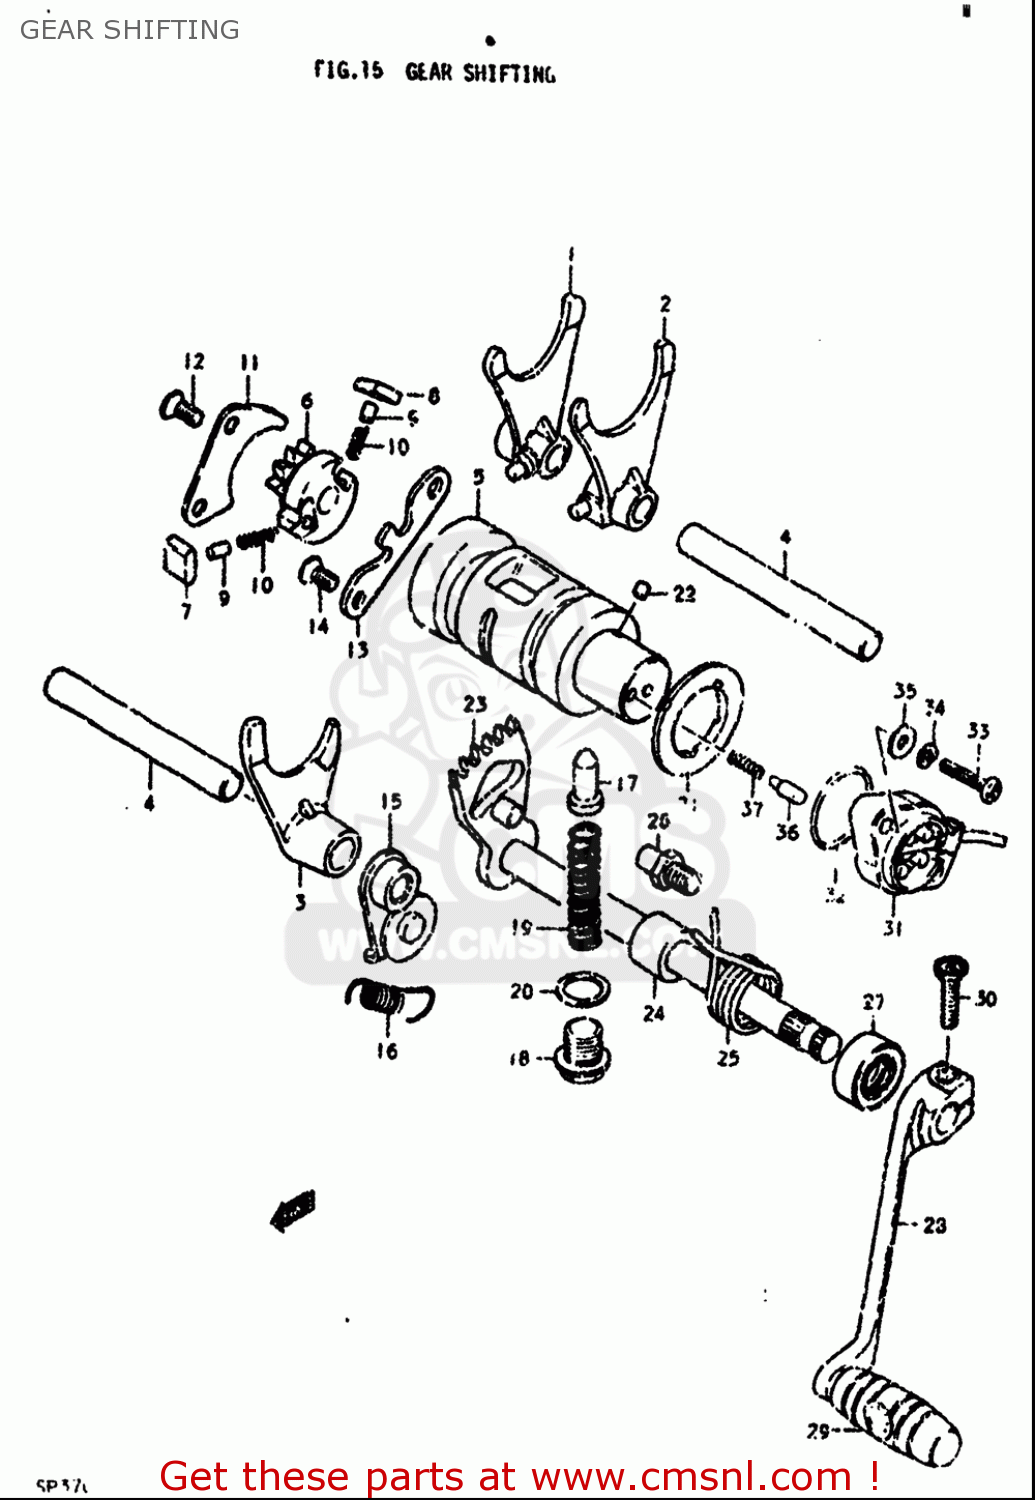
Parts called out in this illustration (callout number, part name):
1	FORK,GEAR SHIFT NO.1
2	FORK,GEAR SHIFT NO.2
3	FORK,GEAR SHIFT NO.3
4	SHAFT,GEAR SHIFT FORK
6	GEAR,GEAR SHIFT CAM DRIVEN
7	PAWL,GEAR SHIFT NO.1
8	PAWL,GEAR SHIFT NO.2
9	PIN(5X8)
10	SPRING
12	SCREW
13	GUIDE,GEAR SHIFT CAM
14	SCREW
15	STOPPER,GEAR SHIFT CAM
16	SPRING
17	STOPPER,GEAR SHIFT CAM NO.2
18	PLUG(MAGNETO)
20	GASKET(14X19.2X2) (NAS)
21	PLATE,GEAR SHIFT CAM STOPPER
22	PIN
24	SPACER(12X20X15.3)
25	SPRING
26	STOPPER,GEAR SHIFT ARM
27	SEAL,OIL (12X22X9)
28	LEVER ASSEMBLY,GEAR SHIFTING
29	RUBBER,GEAR SHIFT PEDAL
30	BOLT
31	TERMINAL BASE,NEUTRAL SWITCH
32	O RING(D:2.4,ID:26.2)
33	SCREW
34	WASHER,LOCK
35	WASHER
36	PIN(5X15.5)
37	SPRING
